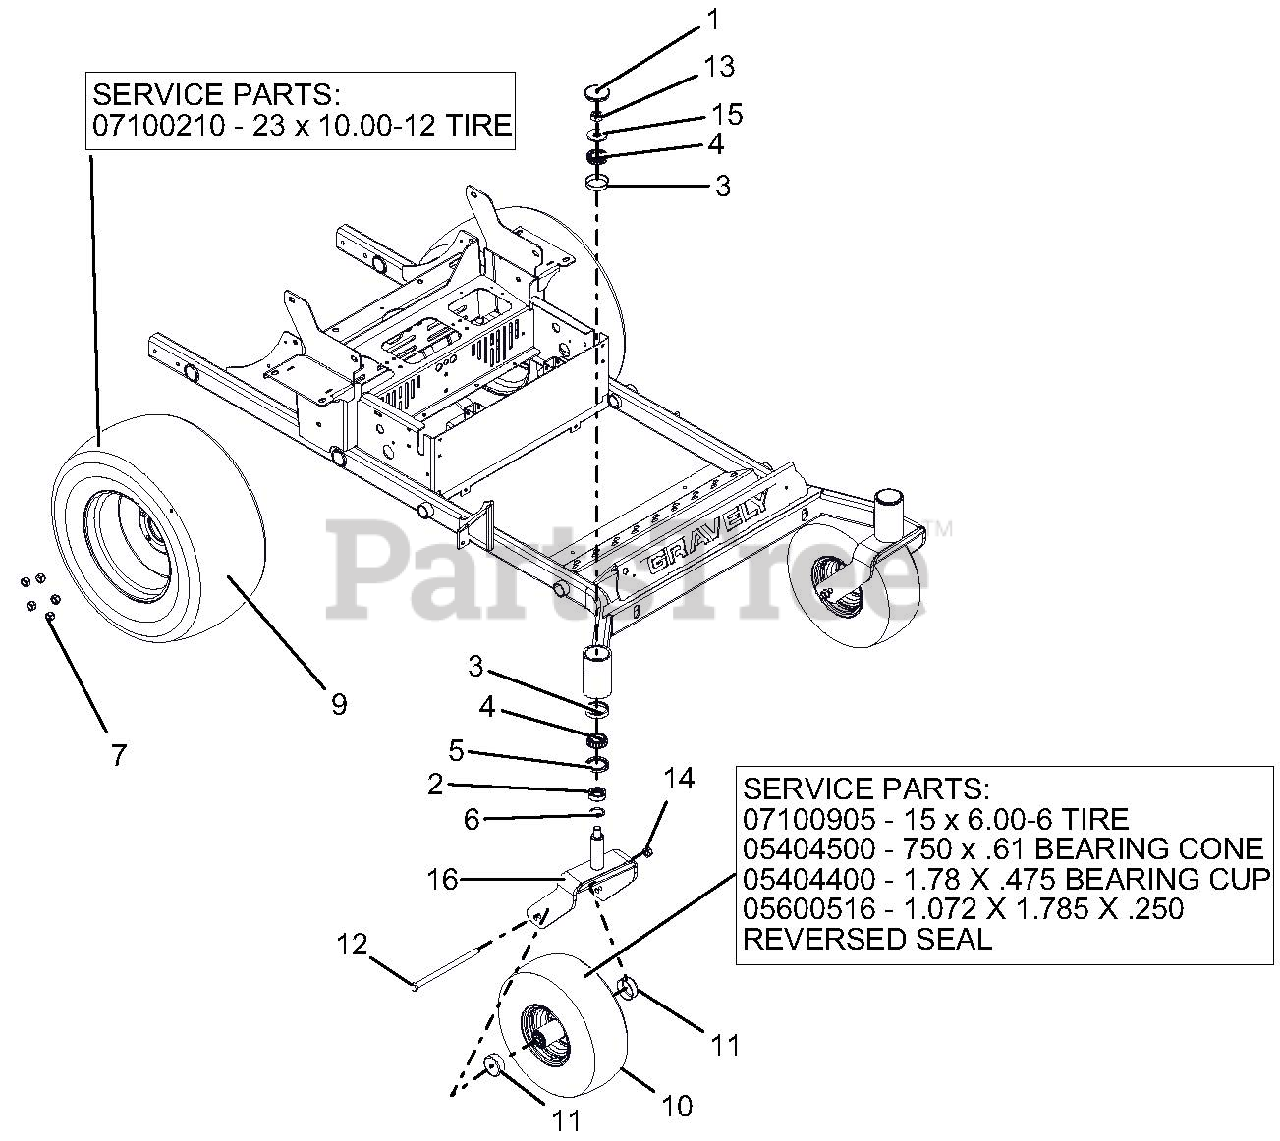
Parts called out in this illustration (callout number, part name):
1	CAP, DUST
2	SPCR, FRONT CASTER FORK
3	BRG, CUP 2.328 X .465
4	BRG, CONE 1.250 X .660
5	SEAL, OIL 1.75 X 2.332 X .312
6	O-RING, .139 W X 1.234 ID
7	NUT, LUG .500-13
9	ASSM TIREWHEEL, 23X10-12
9	23 x 10.00-12 TIRE
10	TIRE/WHEEL, 15 X 6.00-6 SMOOTH
10	15 x 6.00-6 TIRE
10	750 x .61 BEARING CONE
10	1.78 X .475 BEARING CUP
10	1.072 X 1.785 X .250 REVERSED SEAL
11	SHIELD, WHEEL BEARING
12	BLT-HEX .50-13X9.00 GR5 YWZC
13	@NUT-LK-CTR-JAM .75-16 YWZC
14	NUT, LK-TOP-FLG .50-13 YWZC
15	WSHR-FL-STL.812X2.00X.148YWZC
16	WMT, CASTER FORK
